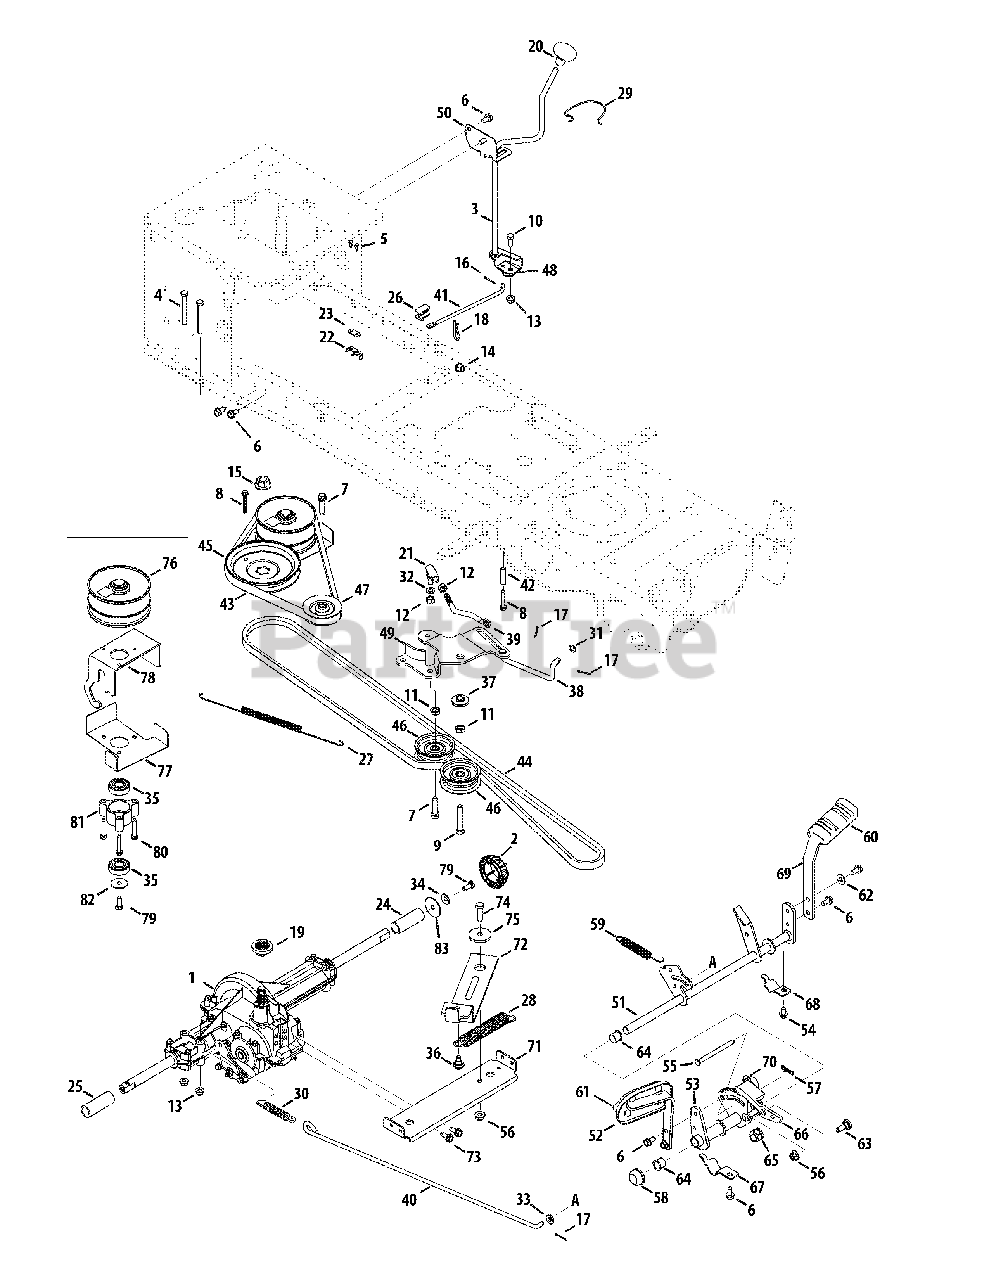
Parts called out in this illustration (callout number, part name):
1	Transaxle Ass’y
2	Hub Cap
3	Shift Lever Ass’y
4	Hex Scr 5/16-18 x 2.75
5	Hex Wash HD AB S-Tapp Scr #8-.50
6	Hex Wash Hd. Tapp Scr. 5/16-18 x .75
7	Hex L-Wash HD Scr 3/8-16 x 1.5
8	Hex TT-Tap Scr 1/4-20 x 1.75
9	Hex Bolt 3/8-16 x 2.25" Lg.
10	Screw-Hex Cap
11	Hex Jam Nut 7/16-20
12	Hex Nut 3/8-24
13	Flange Locknut 5/16-18 Gr. F, Nylon
14	Hex. Flanged L-Nut 3/8-16 Gr. F
16	Int. Cotter Pin .072 x 1.13" Lg.
17	Cotter Pin 3/32 dia x 1.00 Lg.
19	Hub, 5/8" spline
21	Drag Link Ball Joint
22	Short Spring Switch
23	Insulator Nut Plate
24	Sleeve, .758 x .821 x 3.3125
25	Sleeve, .758 x .821 x 2.4375
26	Shift Plate Bearing
27	Extension Spring .70 OD x 12.0
28	Extension Spring .97 OD x 6.18
29	Complete Spring Clip
30	Extension Spring .59 OD x 4.0
31	Flat Washer .385 ID x .62 OD x .06
32	L-Wash 3/8 ID
33	Flat Washer .312 ID x .75 OD
34	Cupped Washer .345 ID x .88 OD x .060
35	Ball Bear ing 17 x 40 x 12
36	Shoulder Screw 5/16-18, .43 x .29
37	Shoulder Spacer 1.375 x .380 x .183
38	Footpedal Bypass Rod
39	Idler Adjustment Rod
41	Shift Rod
42	Spacer .260 x .372 x 1.420
43	V-Belt
44	V-Belt
45	Pulley, V-Type, 7.25 dia.
46	Idler Pulley, Flat 2.75 OD
47	Idler Pulley V-Type x 3.06
48	Shift Adjustment Bracket
49	Idler Bracket (Centre Double)
50	Shift Bracket F-N-R
51	Brake Control Ass’y
52	Auto Drive Pedal Assembly
53	Pedal Bracket Assembly
54	Self-tapping Screw 5/16-18 x .625
55	Clevis Pin 5/16 x 4.02
56	Flange Lock-Nut 3/8-16 Gr. F Nylon
57	Bow-Tie Cotter Pin
58	Push Cap 5/8" Dia Rod
59	Extension Spring .63 dia. x 4.95
60	Brake Pedal Pad
61	Auto Drive Pedal Pad
62	Cupped Washer .345 ID x .88 OD x .060
63	Shoulder Screw .500 x .25
64	Nyliner Flanged Brg.
65	Hex Flanged Bearing .628 ID
67	Pedal Strap Support Bracket
68	Pedal Strap Support Bracket
69	Brake Pedal Bracket
70	Reinforcement Plate Bracket
71	Transmission Bracket Assembly
72	Idler Bracket Ass’y
73	Hex Wash. Hd. Scr. 5/16-18 x .75 Lg.
74	Hex Bolt 3/8-16 x 1.25
75	Shoulder Spacer .884 x .190
76	Variable Speed Pulley Assembly 4.75 OD
77	Belt Keeper Ass’y
78	Variable Bracket Ass’y
79	Hex L-Bolt 5/16-24 x .75 Gr. 5
80	Hex Wash HD Bolt 1/4-20 x 1.50" Lg.
82	Flat Washer .22 ID x 1.25
83	Flat Washer, .350 x 1.59 x .062
